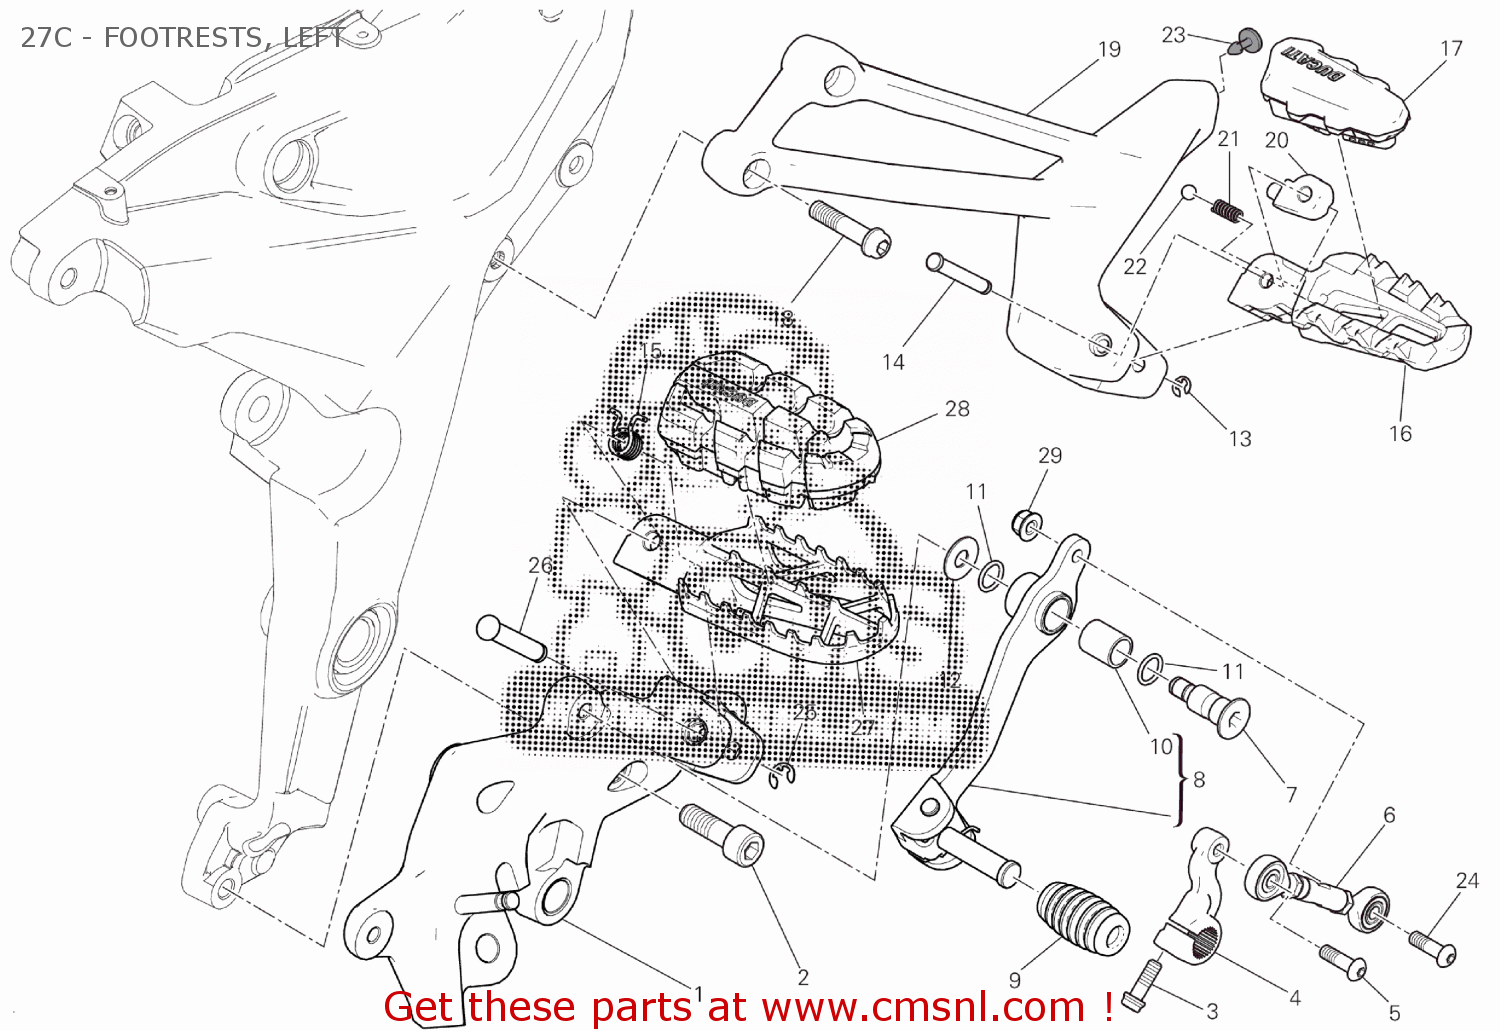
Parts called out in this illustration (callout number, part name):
1	FRONT L.H. PLATE
2	SCREW
3	SCREW TCEIF M6X18
4	GEAR CONTROL LEVER
5	SCREW
6	GEARBOX DRIVING ROD
7	PIN PEDAL
8	GEARCHANGE LEVER
9	RUBBER PAD
10	BUSH
11	O-RING
12	WASHER
13	SPRING RING
14	FOOTREST PIN
15	SPRING. FOOTREST
16	LEFT FOOTREST
17	FOOT PEG RUBBER COVER L.H.
18	SCREW TCEIF M8X35 8.8
19	REAR L.H. PLATE
20	SPRING RETAINER
21	SPRING
22	BALL
23	PLUG
24	SCREW
25	SPRING RING
26	FOOTREST PIN
27	FOOTREST, FRONT LH
28	FOOT PEG RUBBER COVER L.H.
29	NUT 6MM
